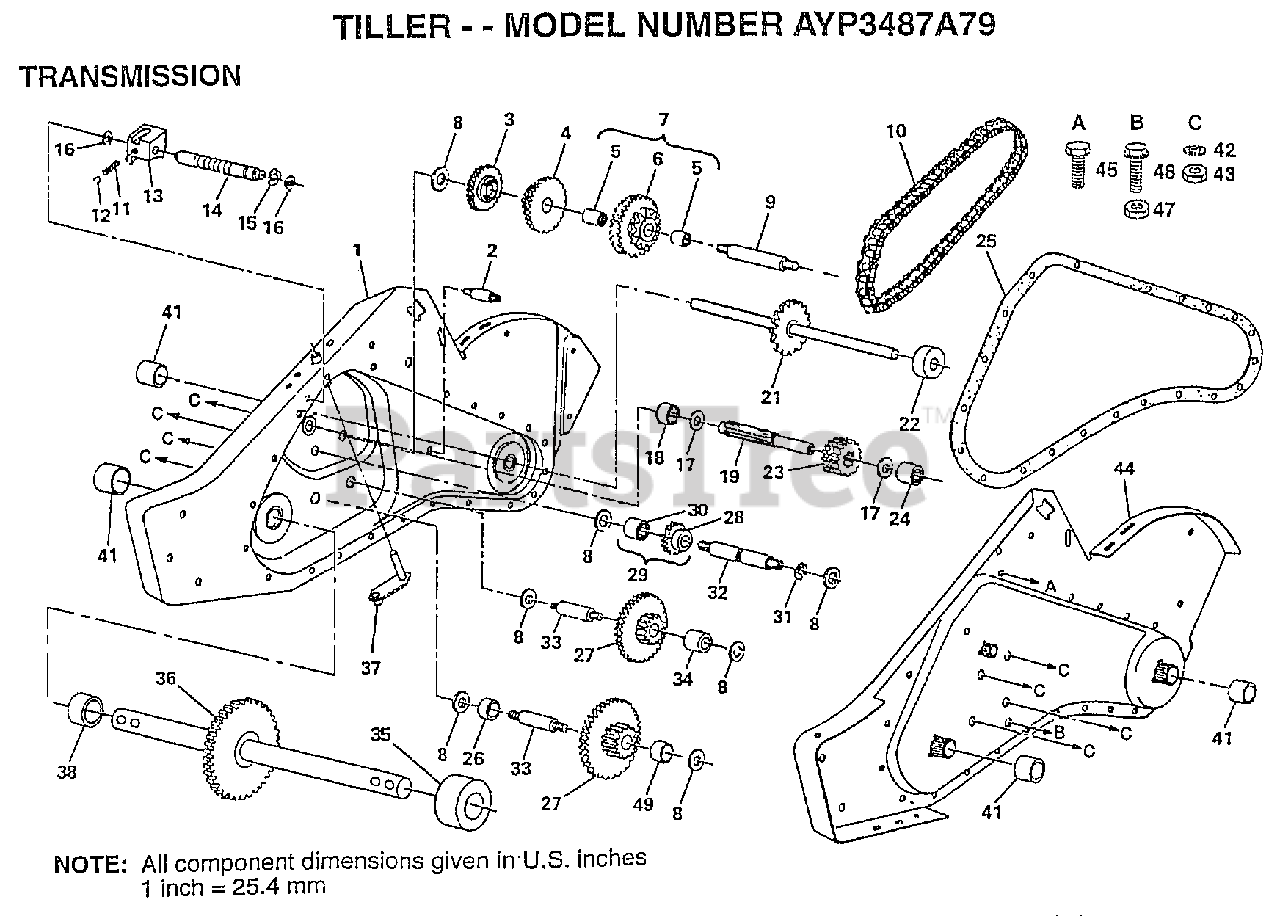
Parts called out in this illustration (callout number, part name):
2	BOLT TI
3	REVERSE GEAR TI
4	CLUSTER GEAR TI
5	"CRT, BEARING"
7	SPROCKET ASSY TI
8	WASHER
9	REDUCTION SHFT TI
10	CHAIN TI
11	SPRING-SHIFT CRT
13	SHIFT FORK TI
14	SHIFT SHAFT TI
15	KLIP RING
16	WASHER SEAL
17	"T, BEARING"
18	"TI, BEARING"
19	SHAFT INPUT
21	SHAFT TINE CRT
22	SPACER CRT
23	INPUT PINION TI
24	NEEDLE BRNG LT
25	GEARCASE GSKT TI
26	SPACER CRT
27	GEAR CLUSTER CRT
28	REVERSE GEAR TI
29	GEAR ASSY TI
30	NEEDLE BEARING TI
31	KLIP RING
32	REVERSE SHAFT TI
33	SHAFT CRT
34	SPACER CRT
35	SPACER CRT
36	SHAFT ASSY CRT
37	BRACKET ASM SHIFT
38	SPACER CRT
41	SEAL ASM-OIL
42	LOCKWASHER
43	NUT.ASF.HEX.7/16
45	SCREW 5/16-18X5/8
47	NUT.HEX.5/16-18
48	BOLT TI
49	SPACER CRT
